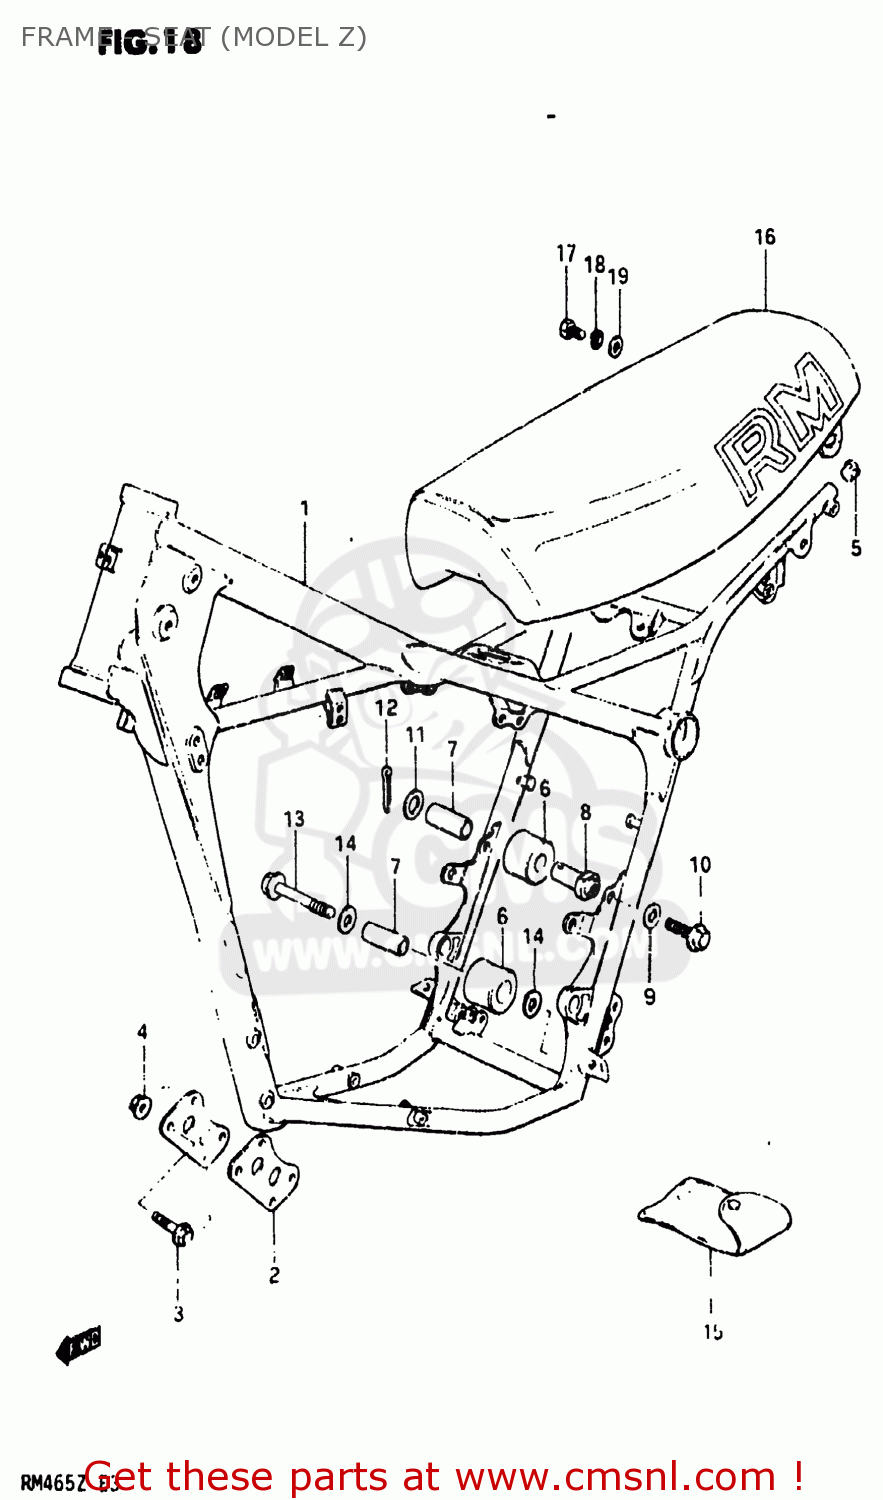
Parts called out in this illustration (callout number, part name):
1	FRAME
2	PLATE,ENGINE MOUNTING
3	BOLT(8X75)
4	NUT
5	PLUG(OD:17)
6	ROLLER,CHAIN LENGTH CONTROL
7	SPACER,CHAIN LENGTH ROLLER
8	BOSS,CHAIN LENGTH ROLL
9	WASHER
10	BOLT
11	WASHER
12	PIN 25X20
13	BOLT(8X45)
14	WASHER
15	TOOL SET
16	SEAT ASSEMBLY
17	BOLT
18	WASHER,LOCK,8.
19	WASHER (8.5X20X2.6)
